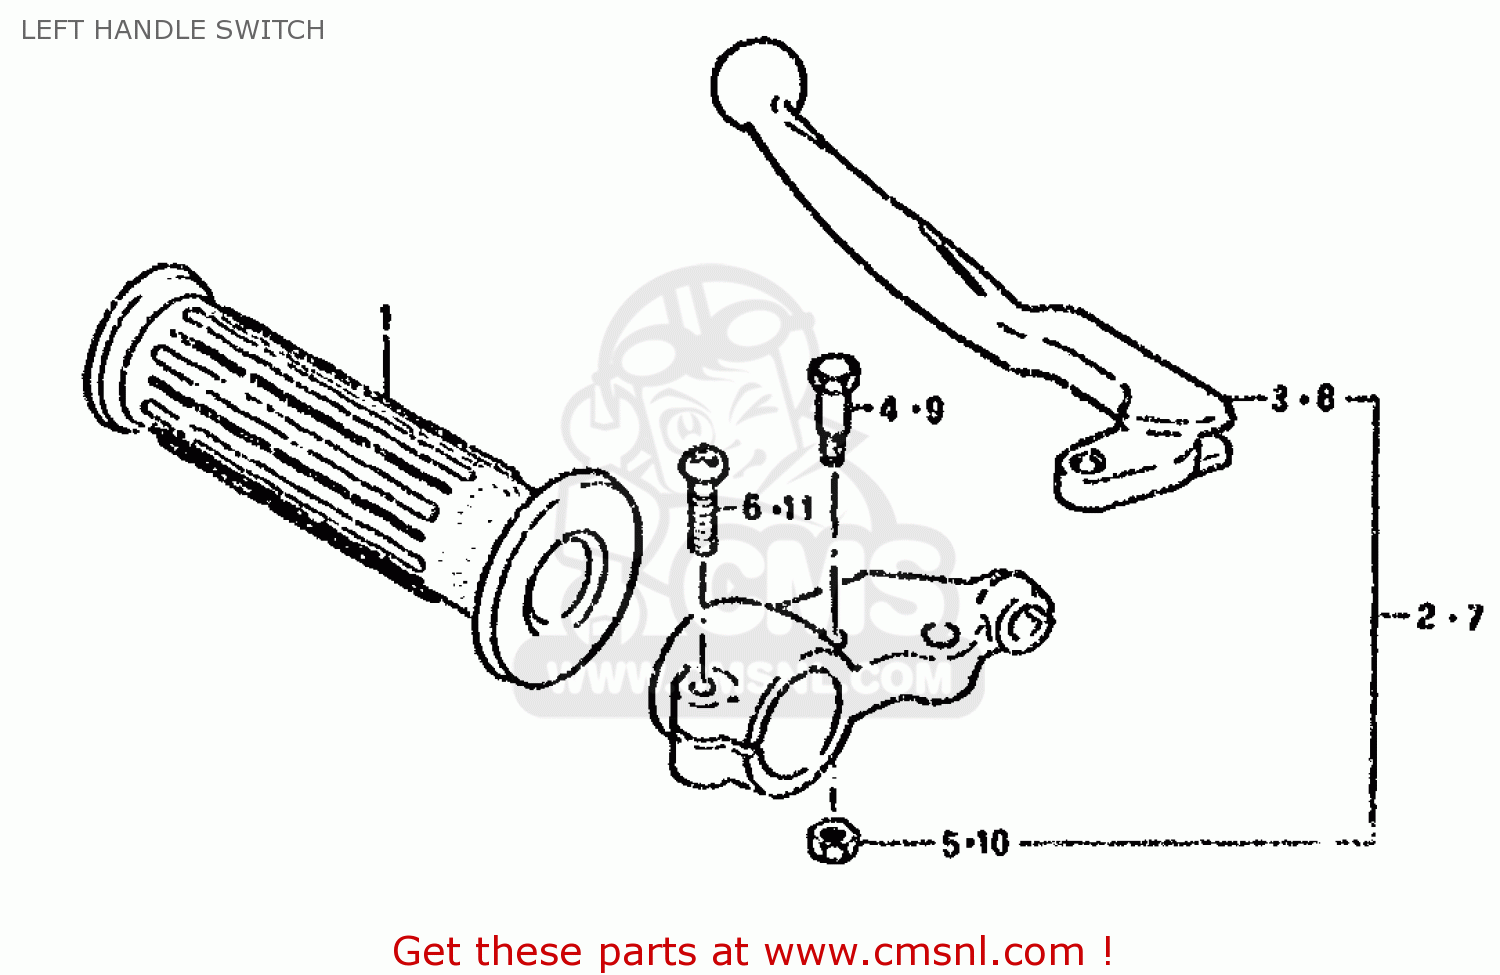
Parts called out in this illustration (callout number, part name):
1	GRIP,L
2	LEVER ASSY,CLUTCH
3	LEVER,CLUTCH
4	BOLT,LEVER PIVOT
5	NUT 5MM
6	SCREW
7	LEVER ASSY,CLUTCH
8	LEVER,CLUTCH
9	SCREW
10	NUT 8MM
11	SCREW
